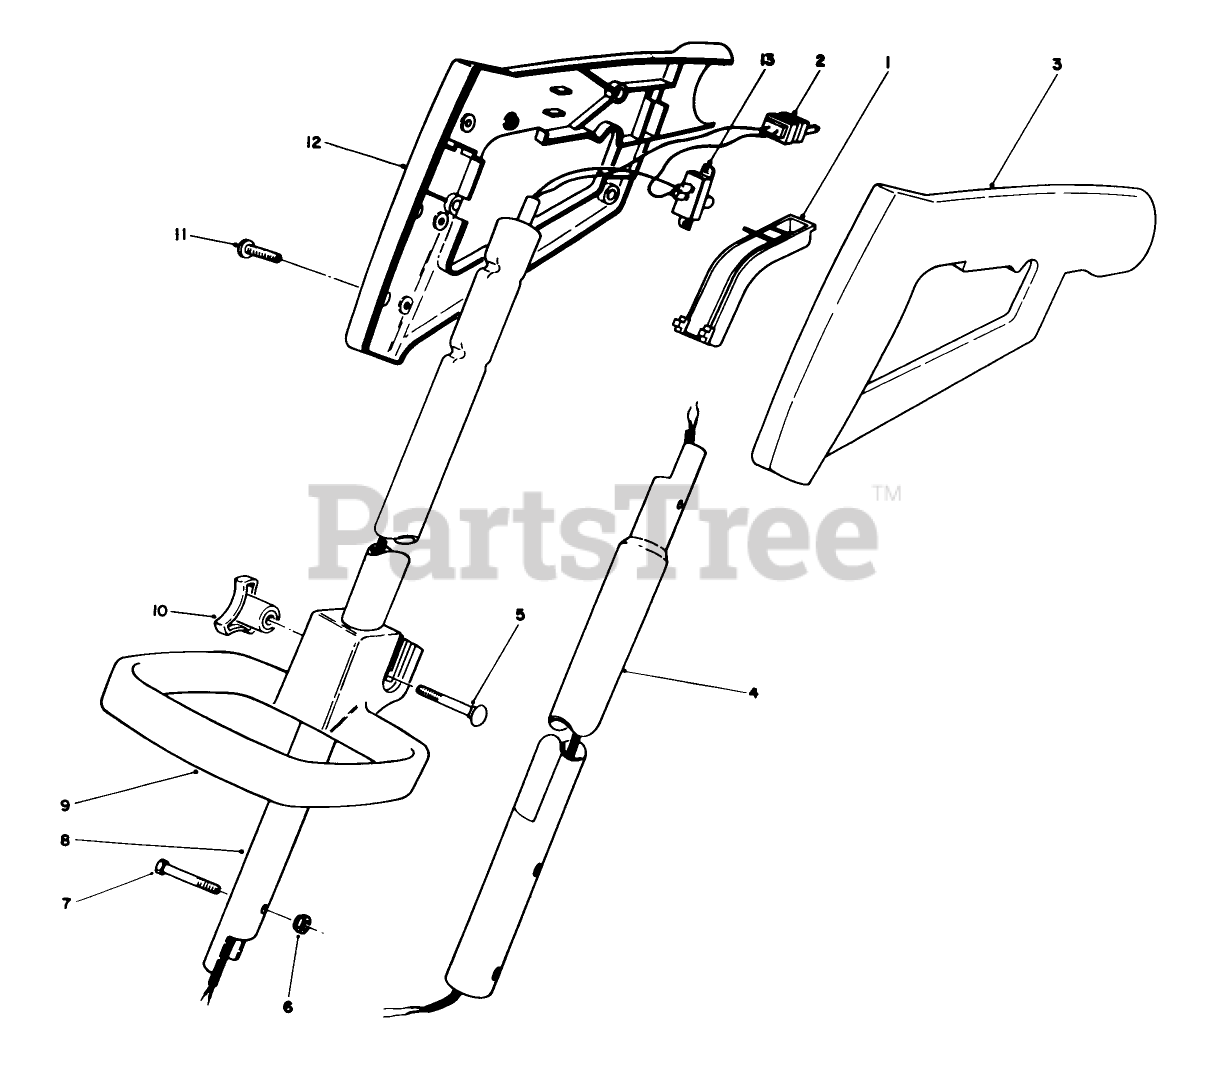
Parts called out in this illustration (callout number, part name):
1	TRIMMER - SWITCH BAR
2	WIRING HARNESS
3	HANDLE GRIP, LH
4	LOWER EXT. TUBE
5	BOLT-CARR
6	NUT-LOCK, NI
7	HEX HD MACHINE SCREW
8	UPPER TUBE
9	Handle-Adjust
10	HANDLE KNOB
11	Screw
12	HANDLE GRIP, RH
13	SWITCH
